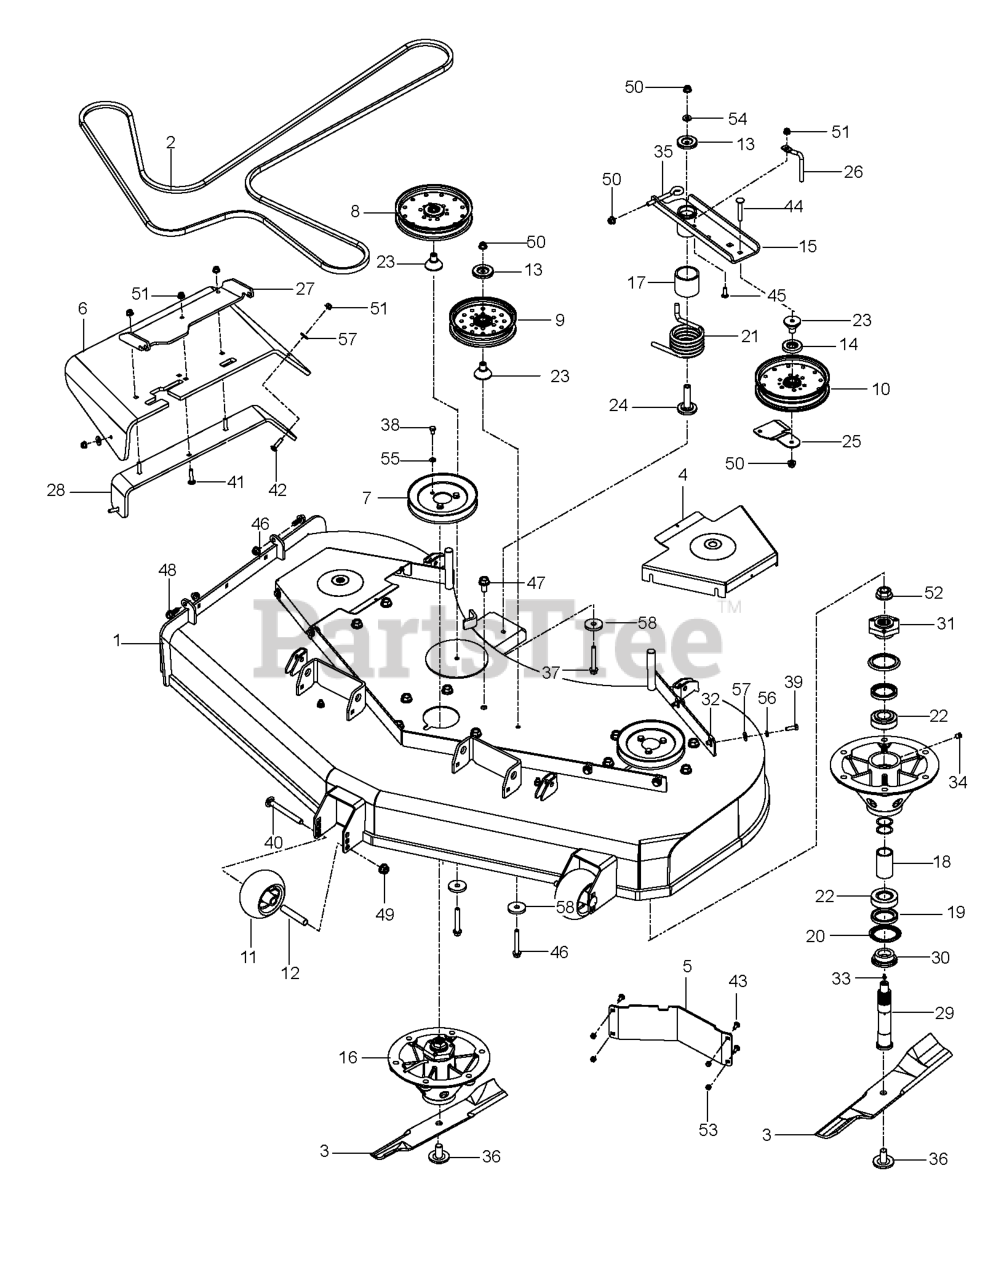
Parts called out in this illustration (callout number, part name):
1	DECK.SVC.W/DECALS.PZT.48"
3	BLADE 17" HIGHT LIFT
4	SHIELD,BELT, 60" ORANGE
5	BAFFLE, DIVERTER 54"/60" LH
6	CHUTE, DISCHARGE 48-52
7	PULLEY - 5.25
8	PULLEY - 7" NARROW
9	PULLEY IDLER, 6" NARROW
10	PULLEY - IDLER 7"
11	ROLLER, GAUGE .635 BORN
12	TUBE, ROLLER AXLE
13	DUST SHIELD
14	SHIELD, DUST
15	IDLER.ARM.BLACK
16	RP_SPINDLE.ASM.10".ALUM.1/8-27
17	SPACER, IDLER PIVOT
19	SEAL SHAFT
20	SEAL V-RING 55MM
21	SPRING, TORSION, IDLER
22	BEARING
23	BEARING, IDLER ARM
24	BEARING, IDLER PIVOT
25	BELT.GUIDE.BLACK
26	BELT KEEPER
27	BRKT - CHUTE MTG BLACK
28	BRKT, CHUTE SUPPORT BLACK
32	U-CLIP 5/16-18 NUT RETAINER
33	ZERK
34	PLUG-VENTED
35	EYE BOLT, 3/8 X 4"
36	BLADE BOLT/WASHER
37	HCS 3/8-16 X 4-1/2 GR 8 ZD
38	HCS 5/16-18 X 1/2 GR 5 ZD
39	BOLT.FIN.HEX.5/16-18UNC X 1.00
40	RHSNB 1/2-13 X 4.75 GR5 ZD
41	BOLT
42	BOLT, CARRIAGE 5/16X1-1/4
43	1/4-20X3/4 CARR BLT
44	CARRIAGE BOLT 3/8-16 X
45	BOLT CRT
46	HHFS 3/8-16 X 2-3/4 GR5 ZD
47	HHFS 1/2-13 X 1 GR5 ZD
48	HHFS 3/8-16 X 1 GRD 5 ZD
49	NUT, 1/2-13 HEX FLG NYLOC ZD
50	NUT 3/8-16 HEX FLG NYLOC ZD
51	5/16-18 NYLOC FLANGE NUT
52	WASHER.LOCK.HVY.HLCL.SPR.5/16
52	NUT FLANGE 3/4-16
53	NUT.1/4-20.HEX.NYLOC.ZD
54	WASHER, 3/8 THICK
55	WASH 5/16 DISC SPRING ZD
56	WASH.5/16.SLW.ZD
57	WASHER.5/16.FLAT.STE.STD.
58	SPINDLE WASHER
